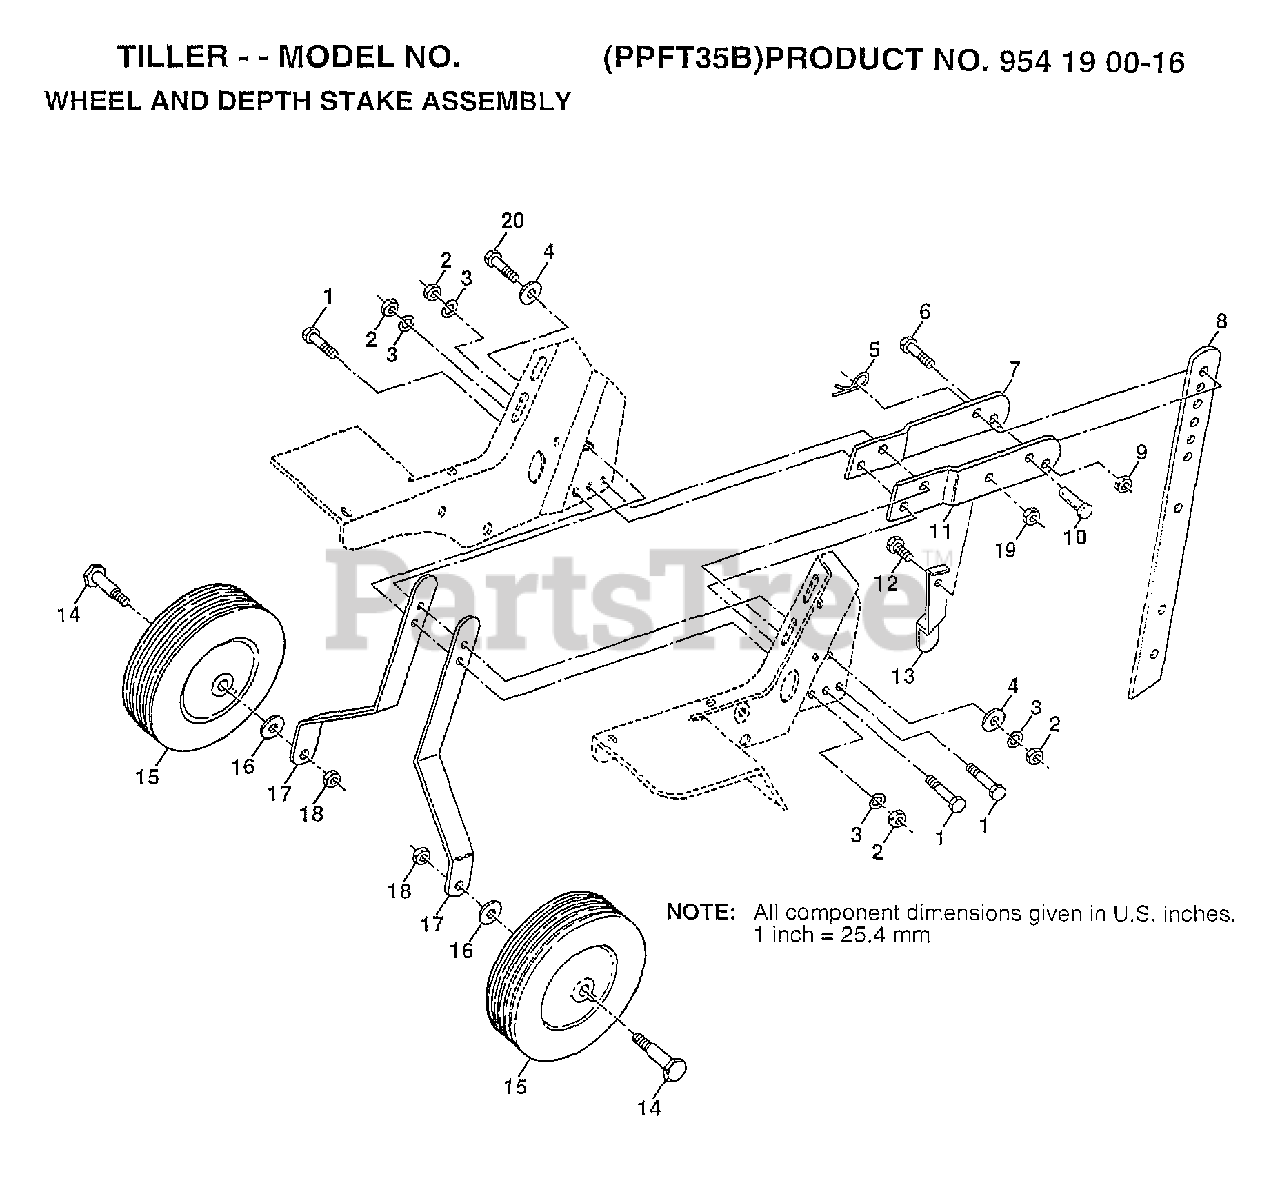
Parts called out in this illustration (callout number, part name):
2	NUT.HEX.5/16-18
3	LOCKWASHER
4	WASHER
5	SPRING.RETAINER
6	BOLT
7	STAKE.SUPT.TILLER
9	NUT
10	DRILLED RIVET RT
12	BOLT
13	STAKE SPRING CT
14	BOLT SHOULDER
15	WHEEL TI
16	WASHER
19	NUT
20	BOLT.HEX.5/16-1.5
